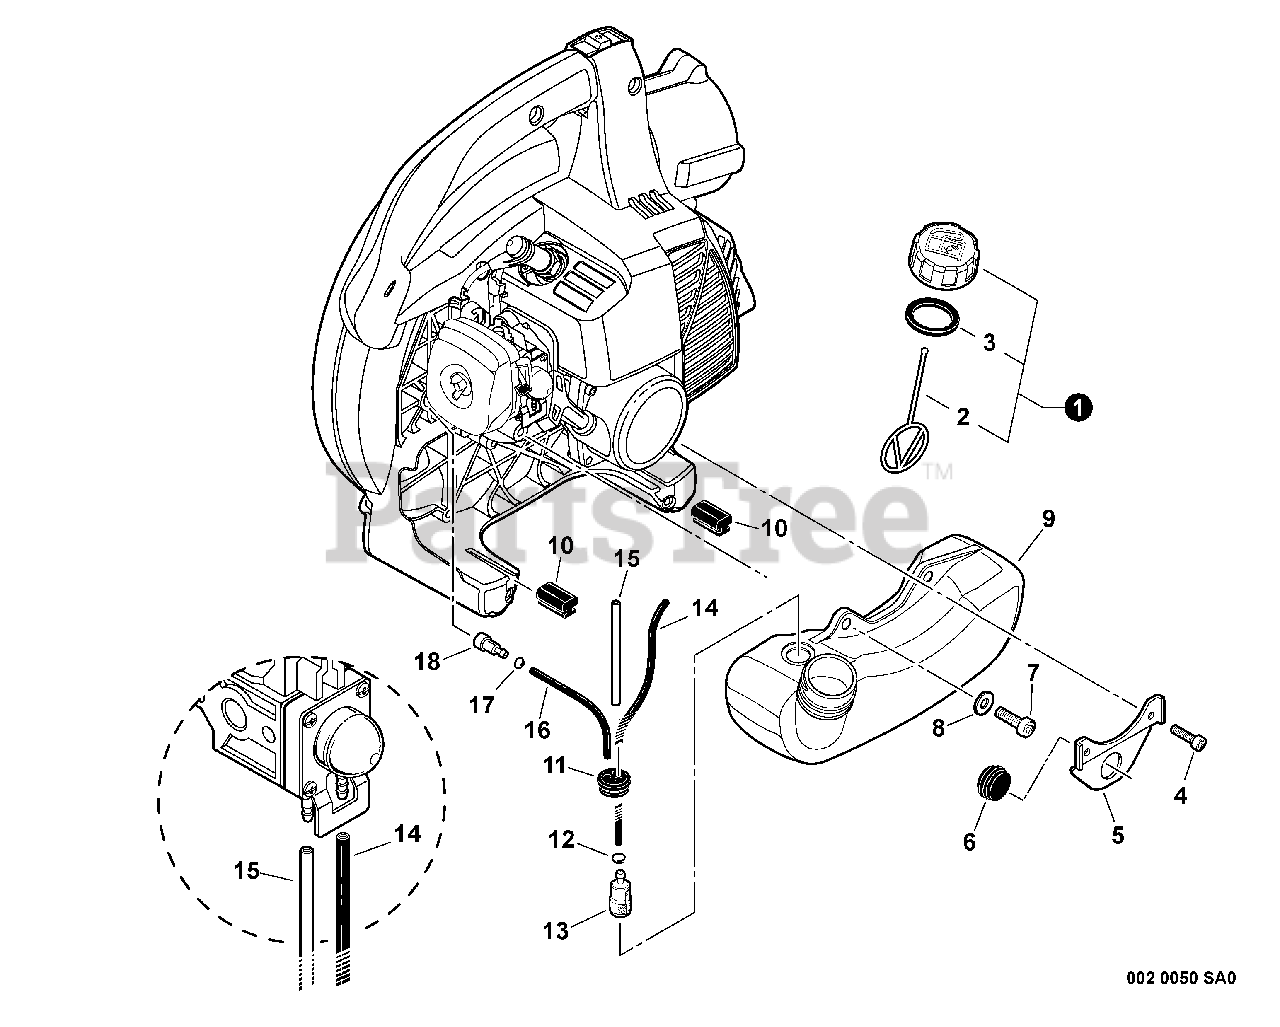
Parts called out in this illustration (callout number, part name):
1	CAP ASSY - ORANGE
2	CONNECTOR, CAP
3	GASKET, CAP
4	SCREW - 4X16
5	BRACKET, FUEL TANK
6	CUSHION
7	SCREW - 5X16
8	WASHER - 5
9	FUEL TANK ASSY
12	CLIP - 6
13	FILTER, FUEL
14	PIPE - 3X5X210 -- BLACK
15	PIPE - 3X6X85 -- CLEAR
16	PIPE - 3X6X80 -- BLACK
17	CLIP - 6
18	VENT, FUEL TANK
